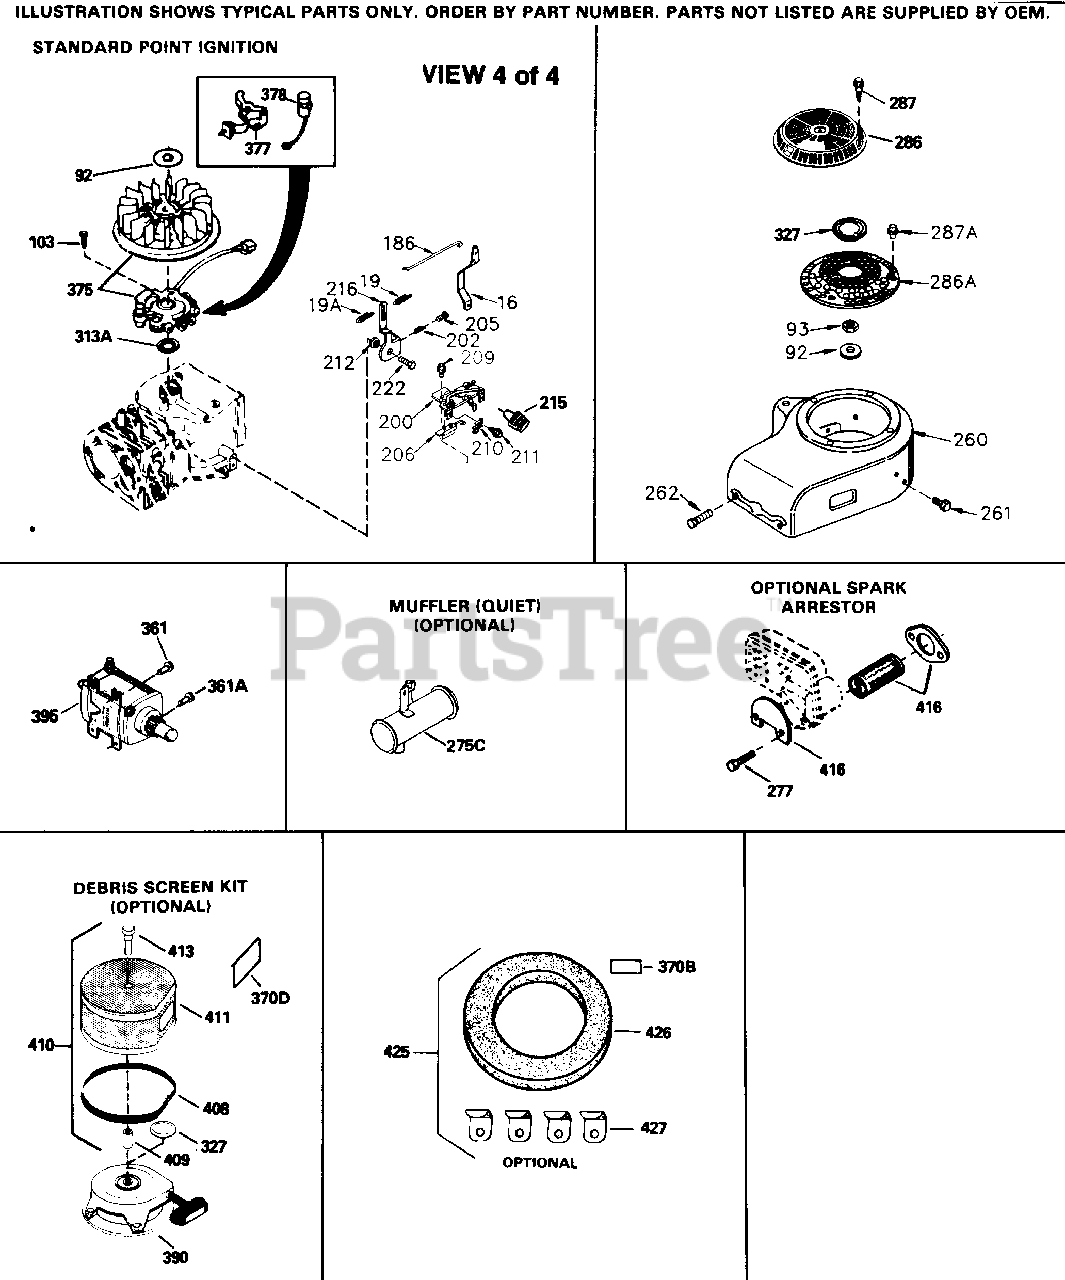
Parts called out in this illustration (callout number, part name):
16	Governor Lever
19	Extension Spring
19A	Extension Spring
51	Counterbalance Weight
62	Screw, 8-32 x 3/8"
92	Lock Washer
93	Flywheel Nut, 5/8-18
103	Screw, Torx T-15, 10-24 x 1"
186	Governor Link
200	Control Bracket
202	Compression Spring
205	Screw, 6-32 x 21/32"
209	Screw, 10-24 x 9/16"
210	Conduit Clip
211	Screw, 10-32 x 3/8"
212	Bushing
216	R.P.M. Adj.Lever Incl. 19,19A,212,222 ,239
222	Screw, 10-32 x 1/2"
238	Screw, 10-32 x 1-17/32"
245A	Pre-Cleaner Air Filter also available in Packaged Part #740015B
260	Blower Housing (for electric starter) NOTE: Replacement hardware may diffe r when servicing starter assy. or blo wer housing. Refer to Service Bulleti n 508.
261	Screw, 5/16-18 x 3/4"
262	Screw, T-40, 5/16-24 x 21/32"
275C	Muffler (quiet) (optional)
277	Screw, 5/16-18 x 3-3/16"
286	Debris Screen
287	Screw, 10-32 x 13/32"
315	Alt. Coil (3 Amp DC) Incl. 321, 322 & 323
327	Starter Plug
408	Screen Seal (Optional)
409	Spacer (Optional)
410	Opt.Screen Kit Incl. 370D,408,409,411 ,413
411	Debris Screen (Optional)
413	Screw, 5/16-18 x 1-5/8" (Optional)
416	Spark Arrestor Kit
425	Starter Muff Kit (Incl. 370,426,427) O pt.
426	Starter Air Cleaner (Optional)
427	Starter Air Cleaner Bracket (Optional )
